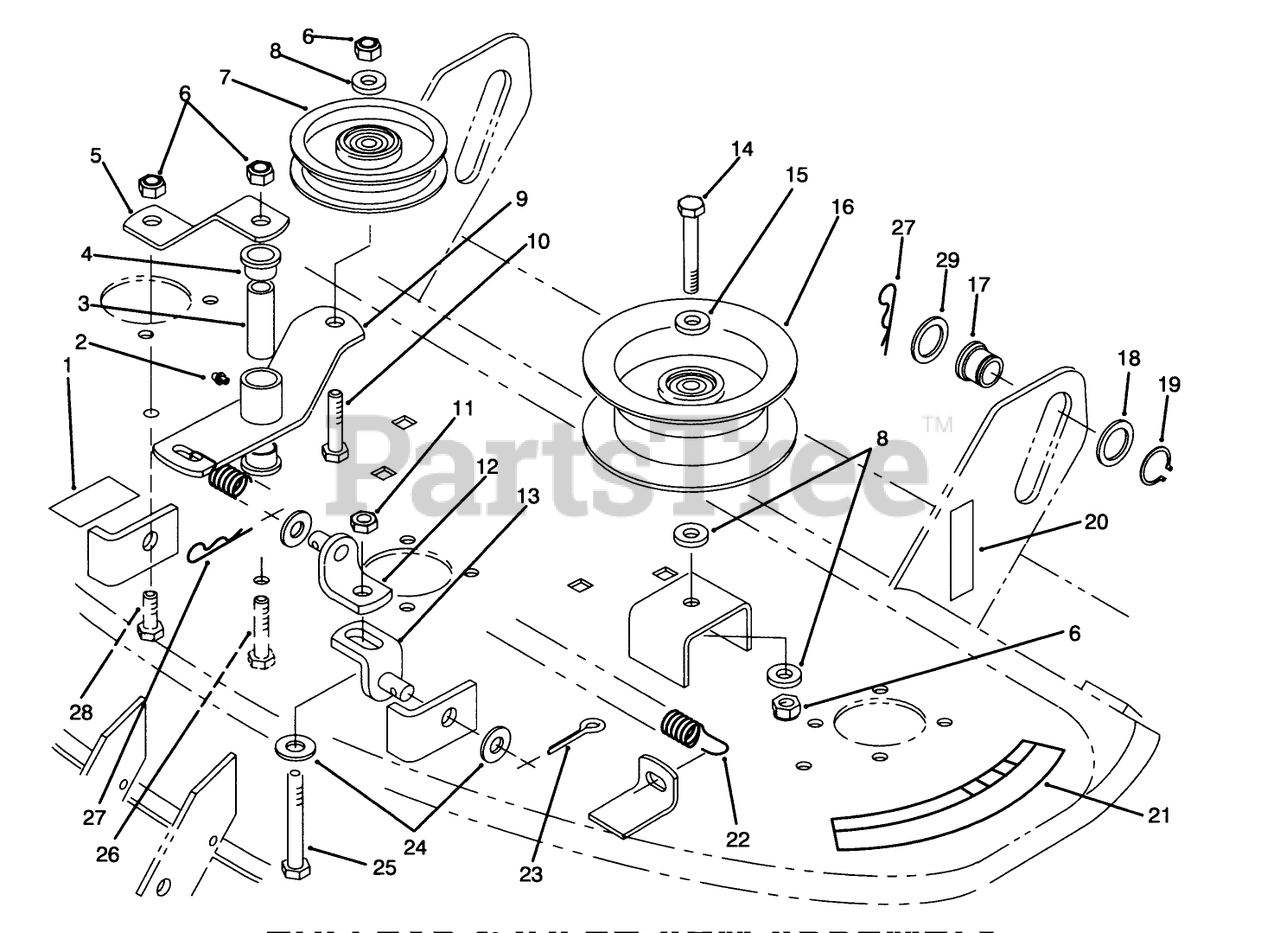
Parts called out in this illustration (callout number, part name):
1	DECAL-BELT INSTALL
2	FITTING-GREASE
3	SPACER
4	BUSHING
5	Strap-Brace
6	NUT-LOCK, NI
7	PULLEY-IDLER, FLAT
8	WASHER-FLAT
9	Arm-Idler
10	SCREW-HH
11	NUT-JAM
12	BRACKET-LIFT, UPPER
13	BRACKET-LIFT, LOWER
14	SCREW-HH
15	WASHER
16	PULLEY-IDLER
17	ROLLER-LIFT
18	Washer
19	RING-RETAINING
20	DECAL-ATTACH-A-MATIC
21	DECAL-DANGER
22	SPRING - EXTENSION
23	PIN-COTTER
24	WASHER-FLAT
25	SCREW-HH
26	SCREW-HH
27	Hairpin
28	SCREW-HH
29	WASHER-FLAT
